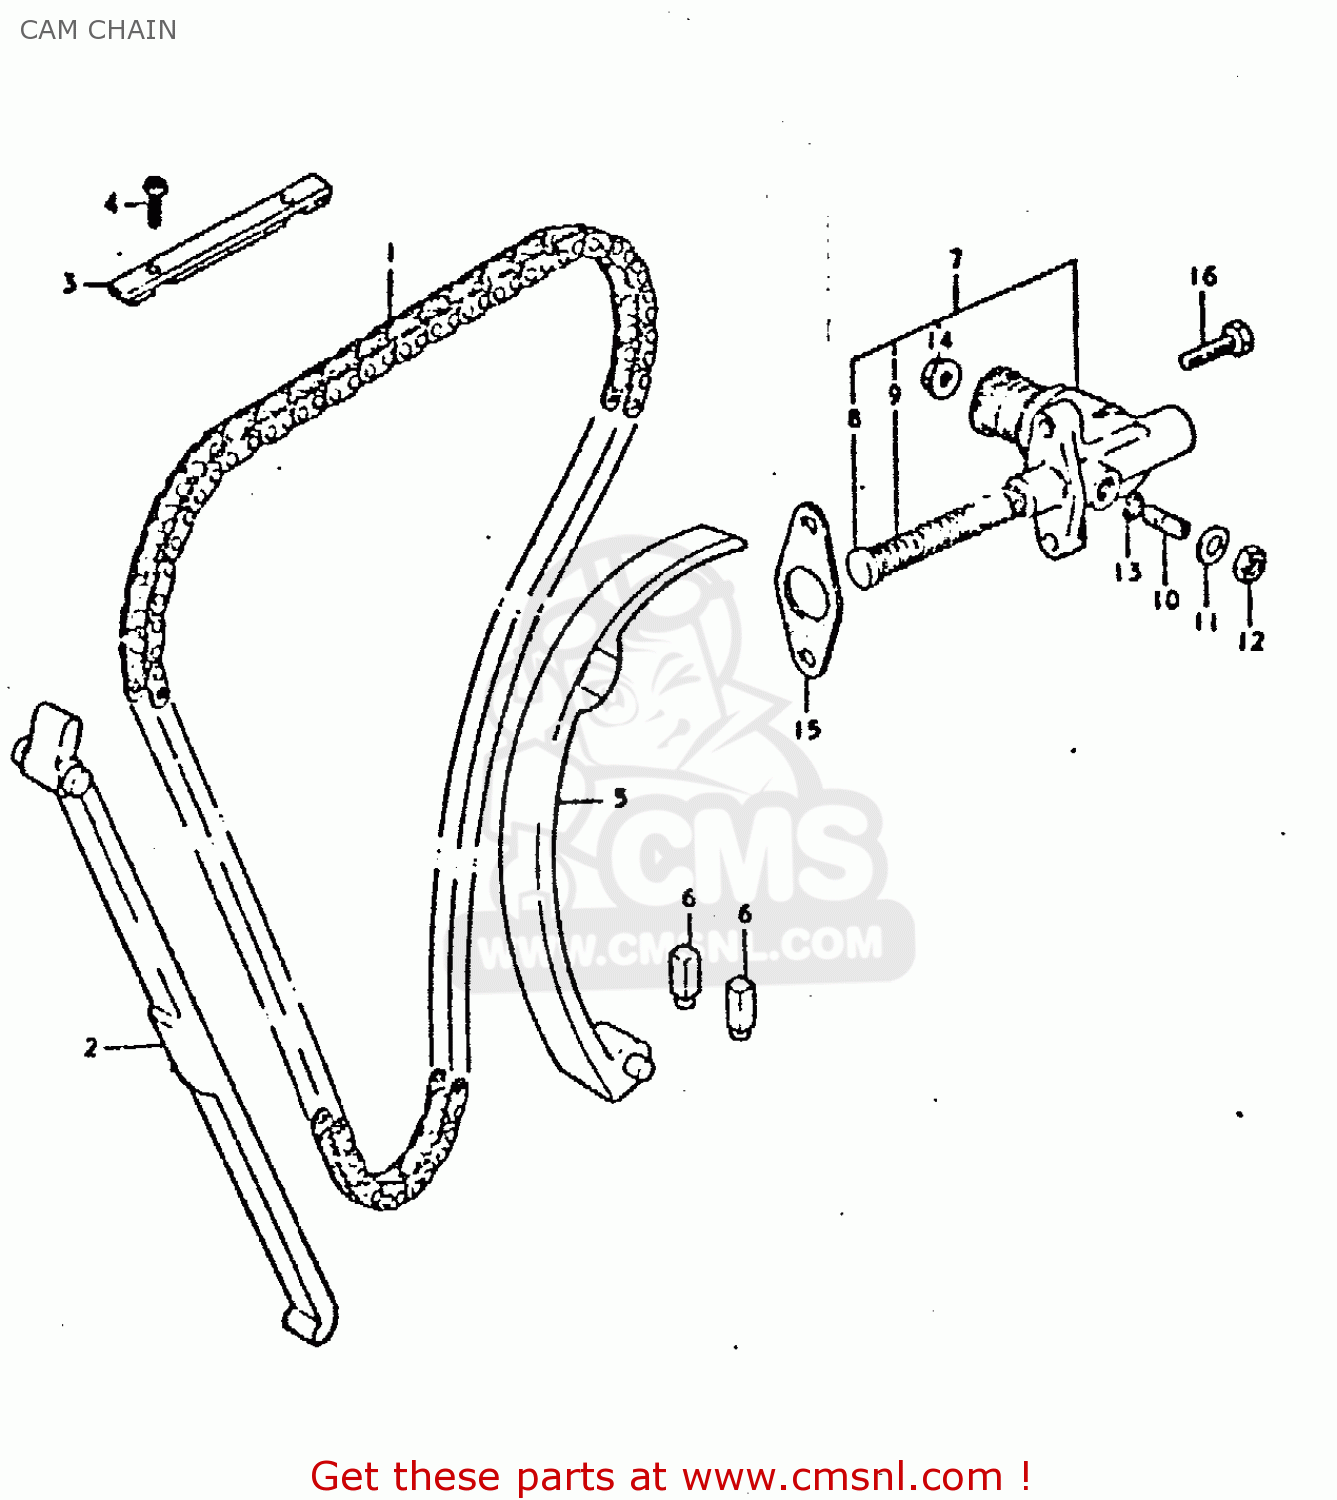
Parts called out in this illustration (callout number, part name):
1	CHAIN,CAMSHAFT DRIVE
2	GUIDE,CAM CHAIN NO.1
3	GUIDE,CAM CHAIN NO.3
4	SCREW
5	TENSIONER,CAM CHAIN
6	CUSHION,CAM CHAIN TENSIONER
7	ADJUSTER ASSEMBLY,TENSIONER
8	ROD,PUSH
9	SPRING
10	SCREW
11	WASHER
12	NUT
13	O-RING
14	NUT
15	GASKET,TENSIONER ADJUSTER (MCA)
16	SCREW (6X25)
